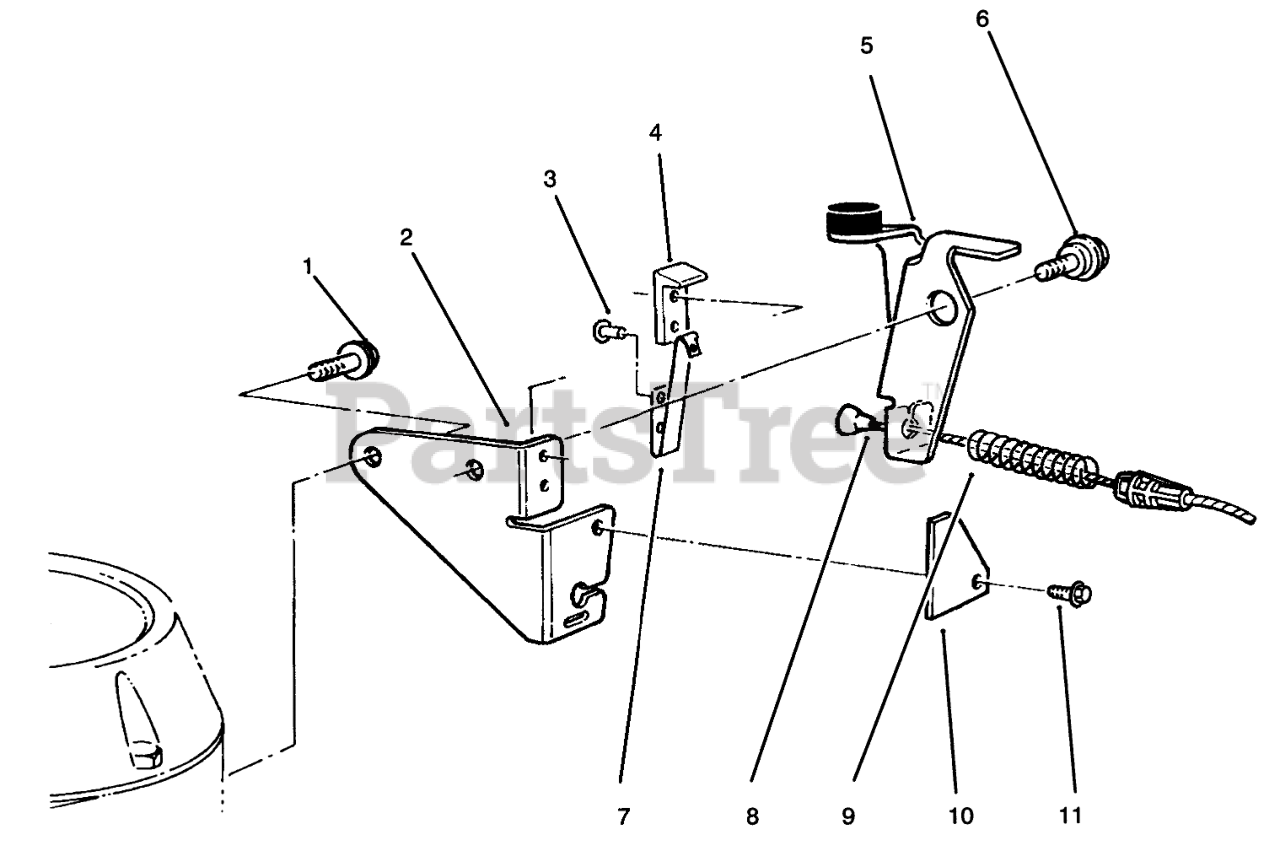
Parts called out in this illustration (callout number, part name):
1	SCREW-HWH
2	PLATE-BRAKE
3	RIVET-PLASTIC
4	STRAP-INSULATING
5	BRAKE PLATE ASM
6	SCREW-SHOULDER
7	STRAP-GROUND
8	Cable-Brake
9	SPRING-COMPRESSION
10	STOP-GROUND STRAP
11	SCREW-HWH
